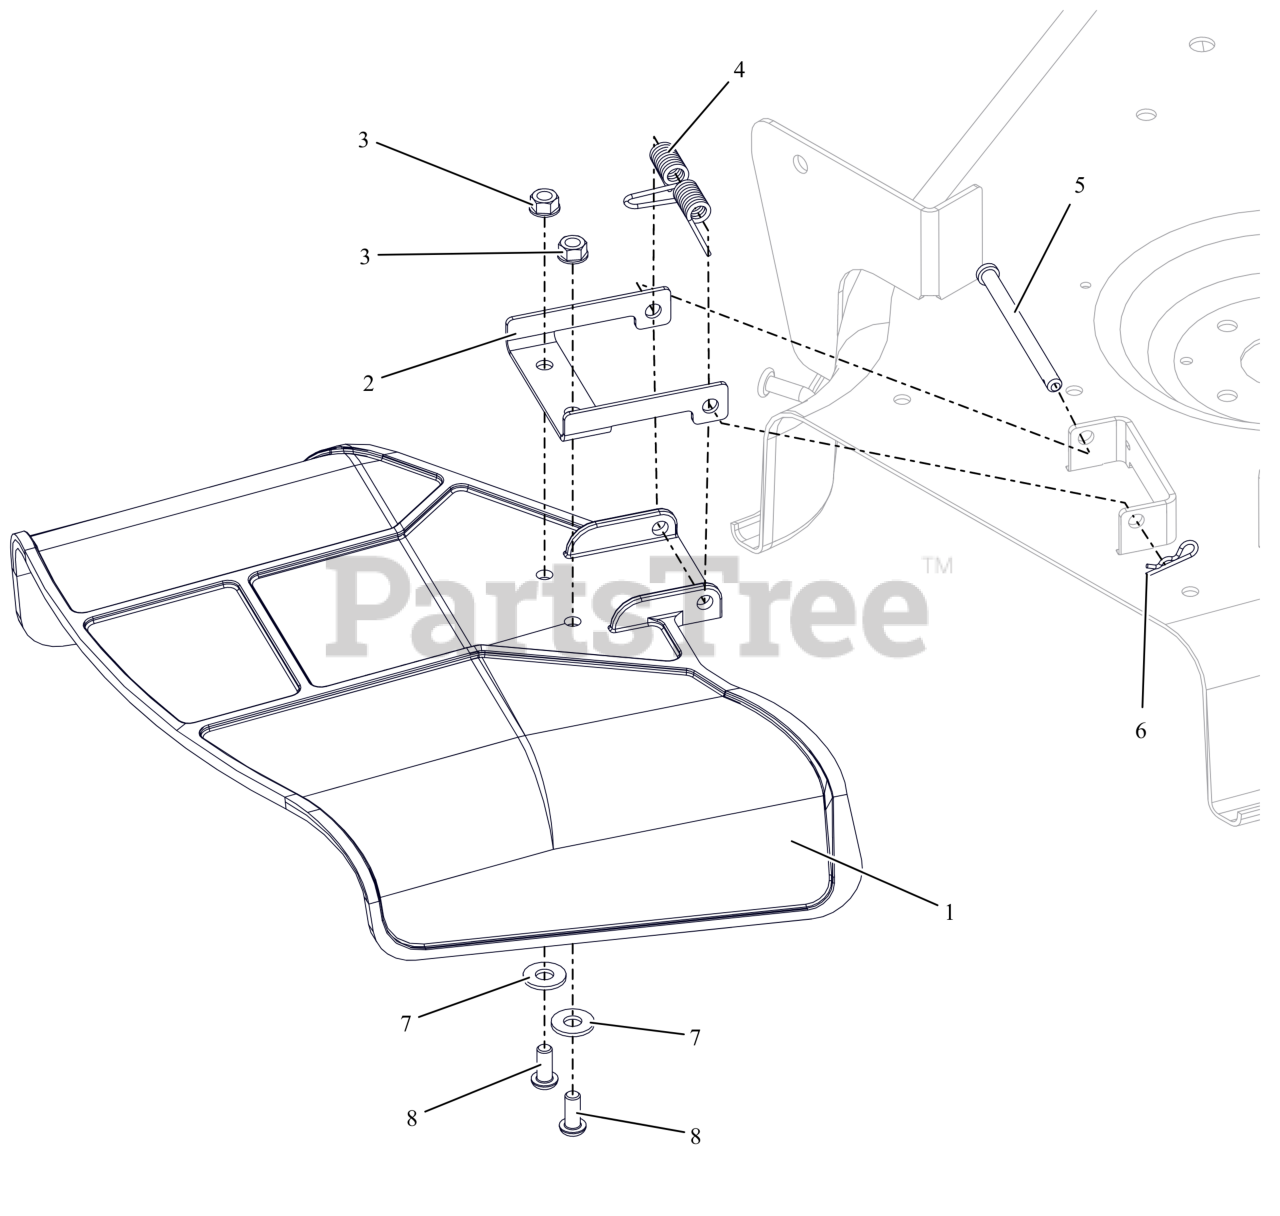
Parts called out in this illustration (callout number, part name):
1	CHUTE, SIDE DISCHARGE
2	CHUTE REINFORCEMENT
3	NUT,LK-CTR-FLG .31-18 GF ZCC
4	SPRING, TORSION
5	PIN, 5/16 X 3.88"
6	PIN, HAIR #213 .08X1.19 ZCC
7	WSHR,FLT .375X.875X.083 ZCC
8	SCR-SKH .31-18X.75 BTNHD YWZC
